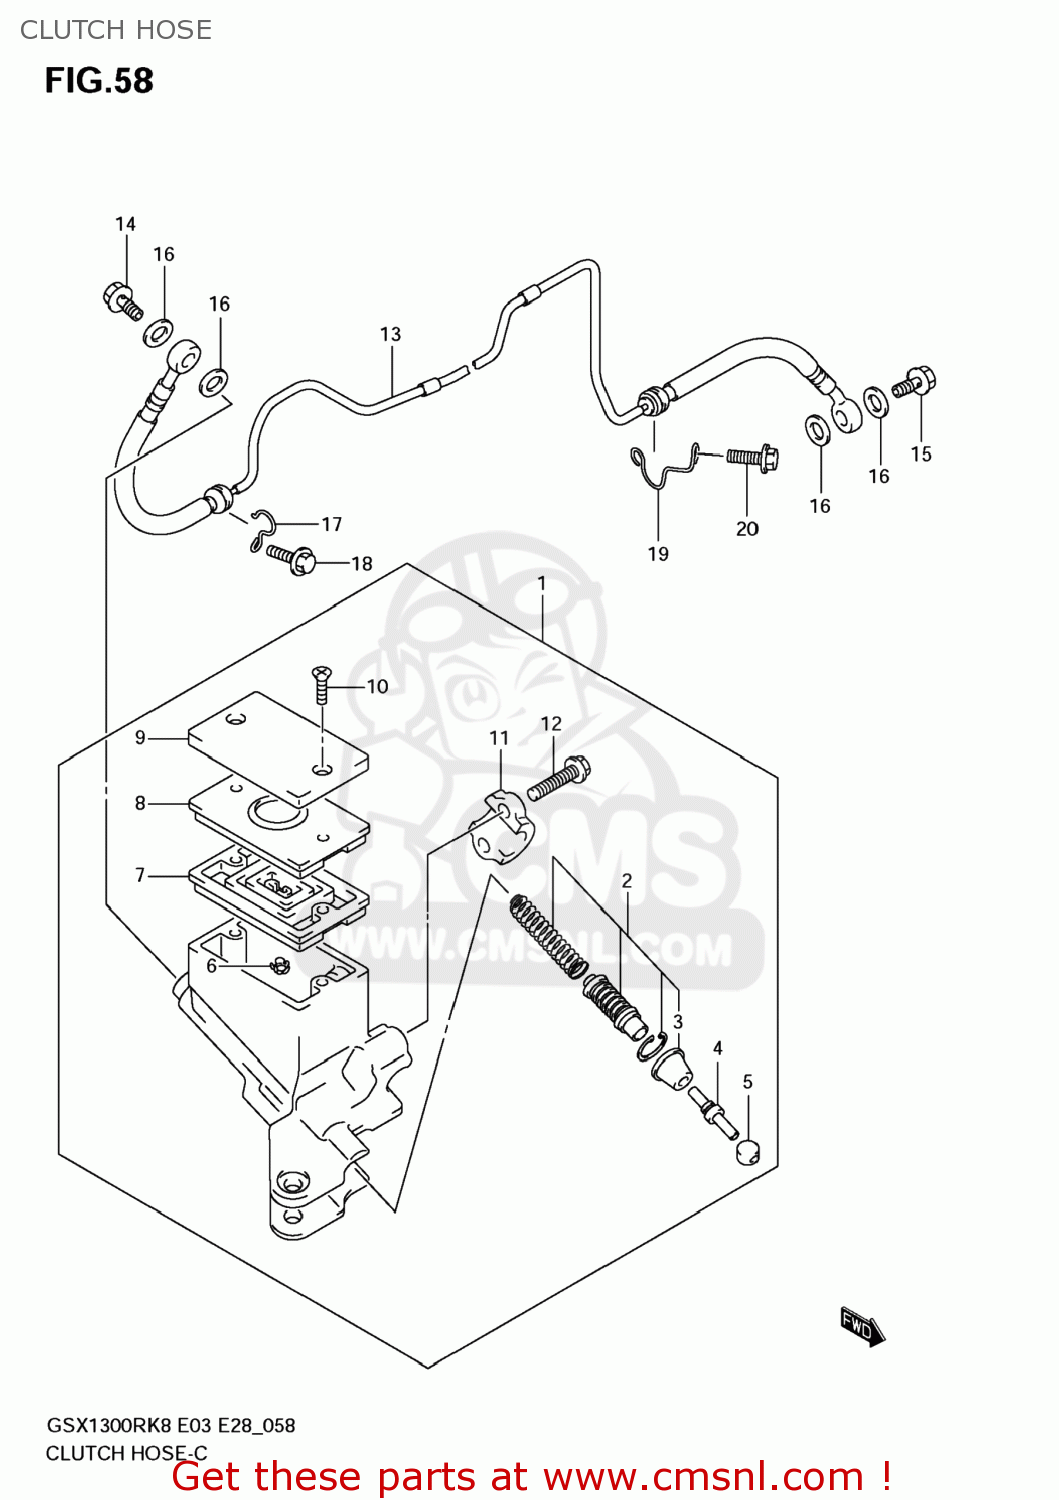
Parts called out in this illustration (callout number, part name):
1	CYLINDER ASSY,CLUTCH MASTER
2	PISTON & CUP SET
3	BOOT
4	ROD,PUSH
5	BUSH
6	PROTECTOR
7	8
8	PLATE,DIAPHRAGM
9	CAP
10	SCREW
11	HOLDER
12	BOLT(6X22)
13	HOSE,CLUTCH
14	BOLT UNION
15	BOLT UNION
16	WASHER(10X15X1.5)
17	CLAMP,CLUTCH HOSE NO.1
18	BOLT
19	CLAMP,CLUTCH HOSE NO.2
20	BOLT
